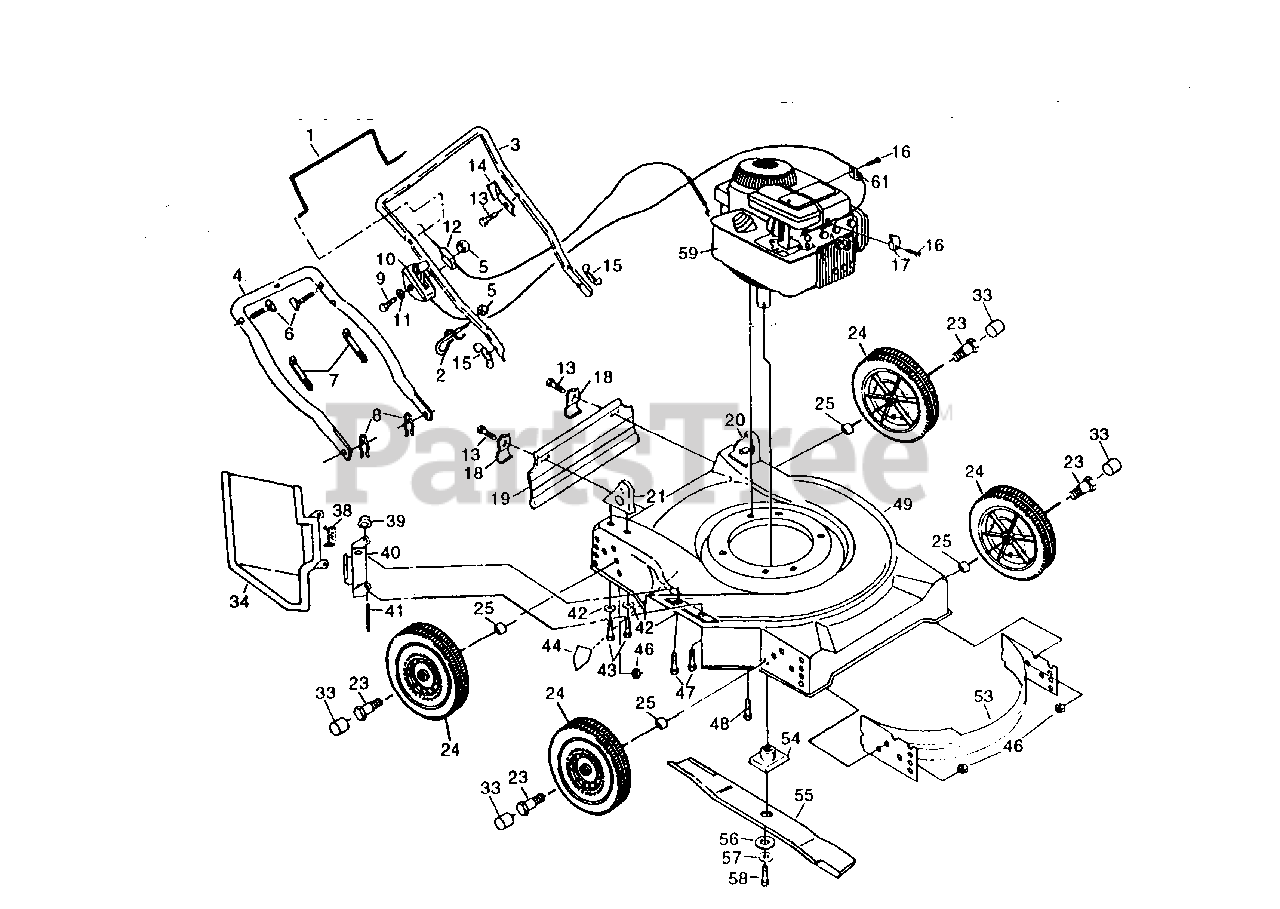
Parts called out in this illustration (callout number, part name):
1	Control Bar (AYP part number)
2	Rope Gulde
3	Upper Handle (AYP part number)
4	Lower Handle (AYP part number)
5	Locknut (AYP part number)
6	Handle Bolt 5/16-18 x 1-3/4 (AYP part number)
7	Wire Tie (AYP part number)
8	Hairpl??n Cotter (AYP part number)
9	Machine Screw 1/4-20 x 2.12 (AYP part number)
10	Throttle Control
11	Washer (AYP part number)
12	Engine Zone Control Cable
13	Hex Washer Head Screw #10-24 x 1/2 (AYP part number)
14	Up-Stop Bracket (AYP part number)
15	Wing Nut (AYP part number)
16	Screw #10 x 5/8 (AYP part number)
17	Cable Clamp (AYP part number)
18	Skirt Bracket (AYP part number)
19	Rear Deflector
20	Handle Bracket Assembly (Left) (AYP part number)
21	Handle Bracket Assembly (Right) (AYP part number)
23	Shoulder Bolt 3/8-16 x 2-1/2 (AYP part number)
24	Wheel Assembly (AYP part number)
25	Wheel Spacer
33	Hubcap (AYP part number)
34	Discharge Guard
38	Torslon Spring (AYP part number)
39	Push On Speed Nut (AYP part number)
40	Deflector Hinge (AYP part number)
41	Hinge Rod (AYP part number)
42	Flat Washer (AYP part number)
43	Screw 5/16-18 x 3/4 (AYP part number)
44	Danger Decal (AYP part number)
46	Locknut 3/8-16 (AYP part number)
47	Hex Head Thd. Rolling Screw 1/4-20 x 3/4 w/ Sems (AYP part number)
48	Hex Head Thread Rolling Screw 3/8-16 x 1 (AYP part number)
49	Mower Housing
53	Front Baffle (AYP part number)
54	Blade Adapter (AYP part number)
55	Blade 20"
56	Hardened Washer (AYP part number)
57	Helical Lockwasher 3/8 (AYP part number)
58	Hex Head Screw 3/8-24 x 1-3/8 (Grd. 8)
61	Guide Clip (AYP part number)
